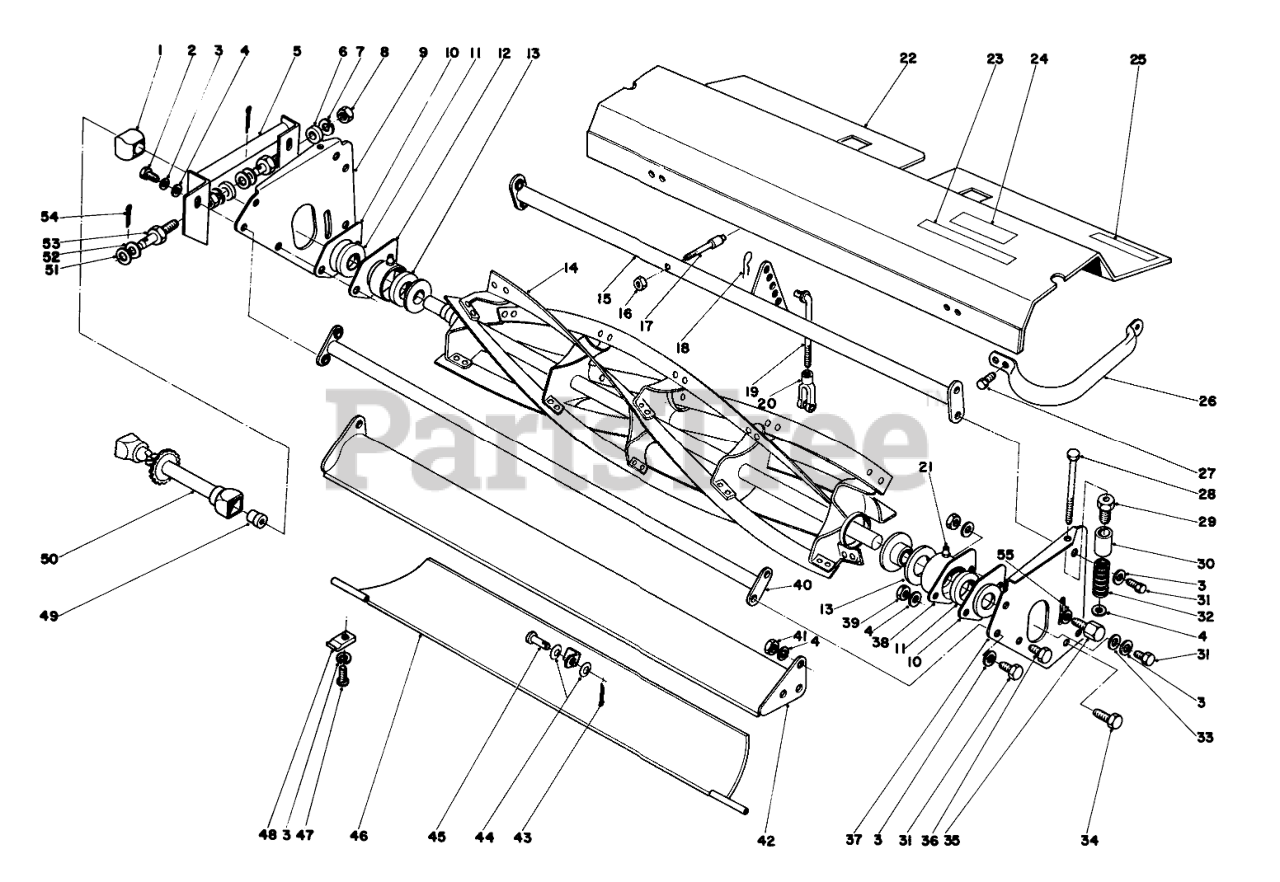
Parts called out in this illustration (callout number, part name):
1	DRIVE BALL
2	SCREW-HH
3	WASHER-LOCK, INTERNAL
4	WASHER-PLAIN
5	Hitch Left Hand
6	SPHERICAL SPACER
7	WASHER-LOCK
8	NUT-HEX
9	Side Plate
10	Cup-Bearing
11	.6693 RP BALL BEARING
12	Cup Bearing
13	1 X .250 OIL SEAL
14	Reel Assy.-LeftWing
15	Tube Reel
16	NUT-KEPS
17	Pin-Link
18	PIN-COTTER
19	Rod Adjusting
20	YOKE
21	FITTING-GREASE
22	Shield Grass
23	Decal
24	Decal
25	WARNING DECAL
26	Guard-Reel
27	10-16 X 3/8 THDG SCREW
28	Screw-Adjusting
29	Bolt-Adjusting
30	ADJUSTMENT BLOCK
31	SCREW-HH
32	SPRING-COMPRESSION
33	WASHER-FLAT
34	SCREW-HH
35	REEL BEARING SCREW
36	BEARING CUP BOLT
37	Side Plate
38	Cup Bearing
39	NUT-LOCK
40	Tube-Reel
41	NUT-HEX
42	Bedknife
43	PIN-COTTER
44	WASHER-SPRING
45	PIN-CLEVIS
48	CLIP-SKID
49	REEL DRIVE PAD
50	Shaft-Reel Drive
51	COLLAR
52	9/16ID X 032 WASHER
53	PIVOT STUD
54	PIN-COTTER
55	WASHER
